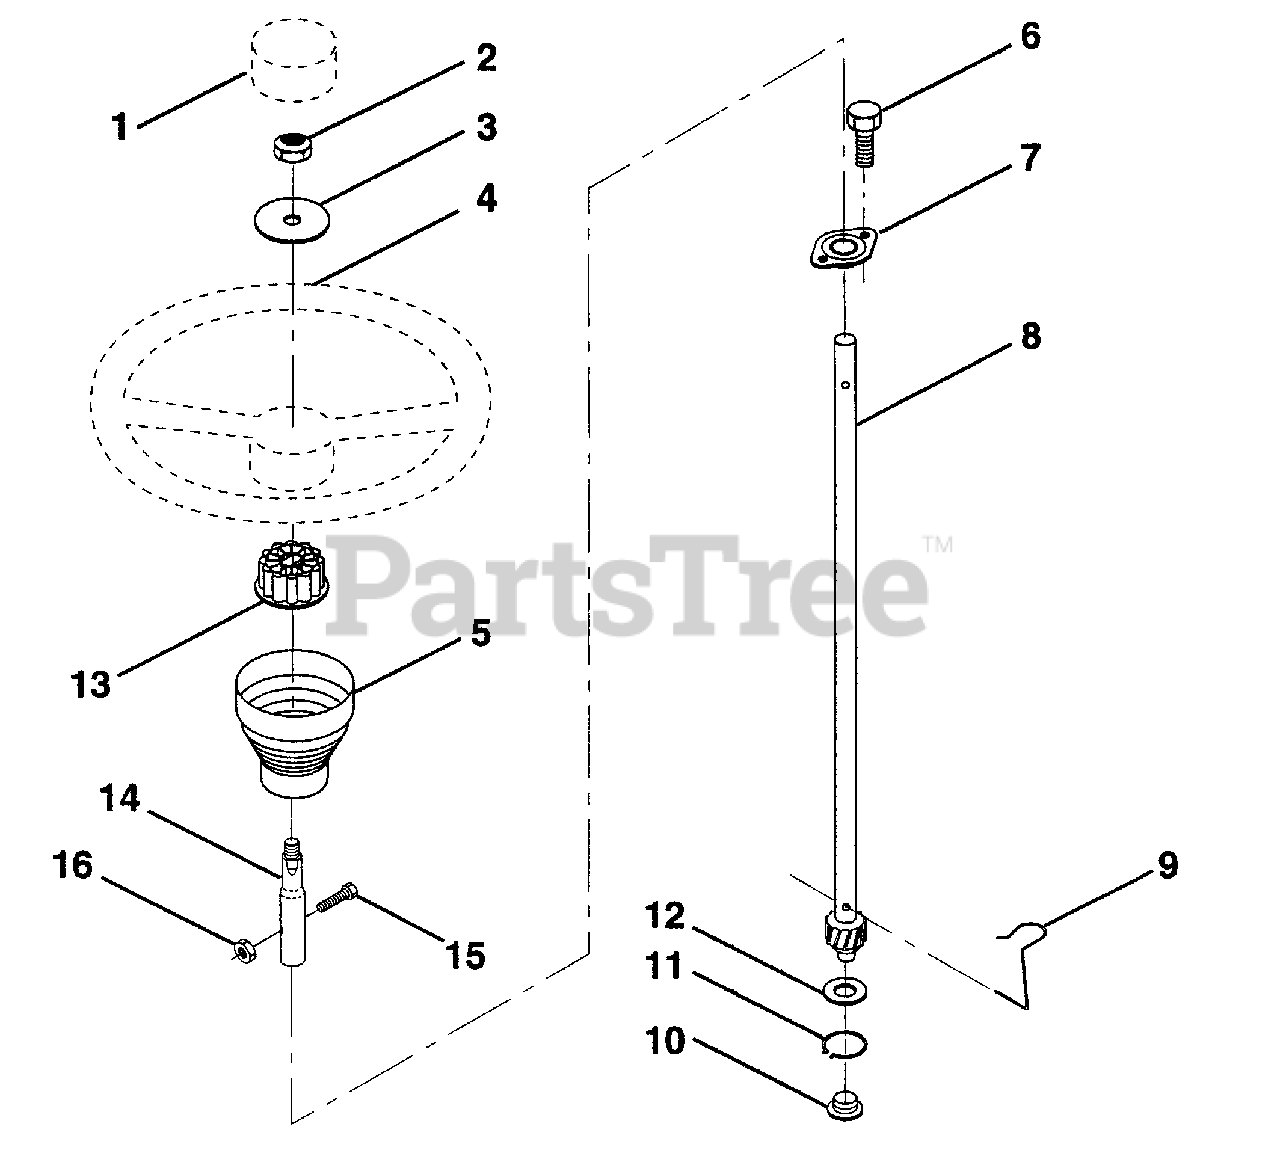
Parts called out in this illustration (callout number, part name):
1	Insert, Steering Wheel
2	Locknut 3/8-24 UNF
3	Washer 12/32 x 2-3/8 x 8 Gauge
4	Steering Wheel
5	Sleeve, Steering
6	Screw, Hex Head #10-16 x 1/2
7	Bushing, Steering
8	Shaft, Steering
9	Clip, Steering
10	Bushing, Lower, Steering
11	Ring, Retaining
12	Washer 21/32 x 1 x 16 Gauge
13	Adaptor, Steering Wheel
14	Extension Shaft Steering
15	Bolt Fin Hex 5/16-18 Unc x 1-1/4
16	Nut, Lock Hex w/Ins 5/16-18 Unc
